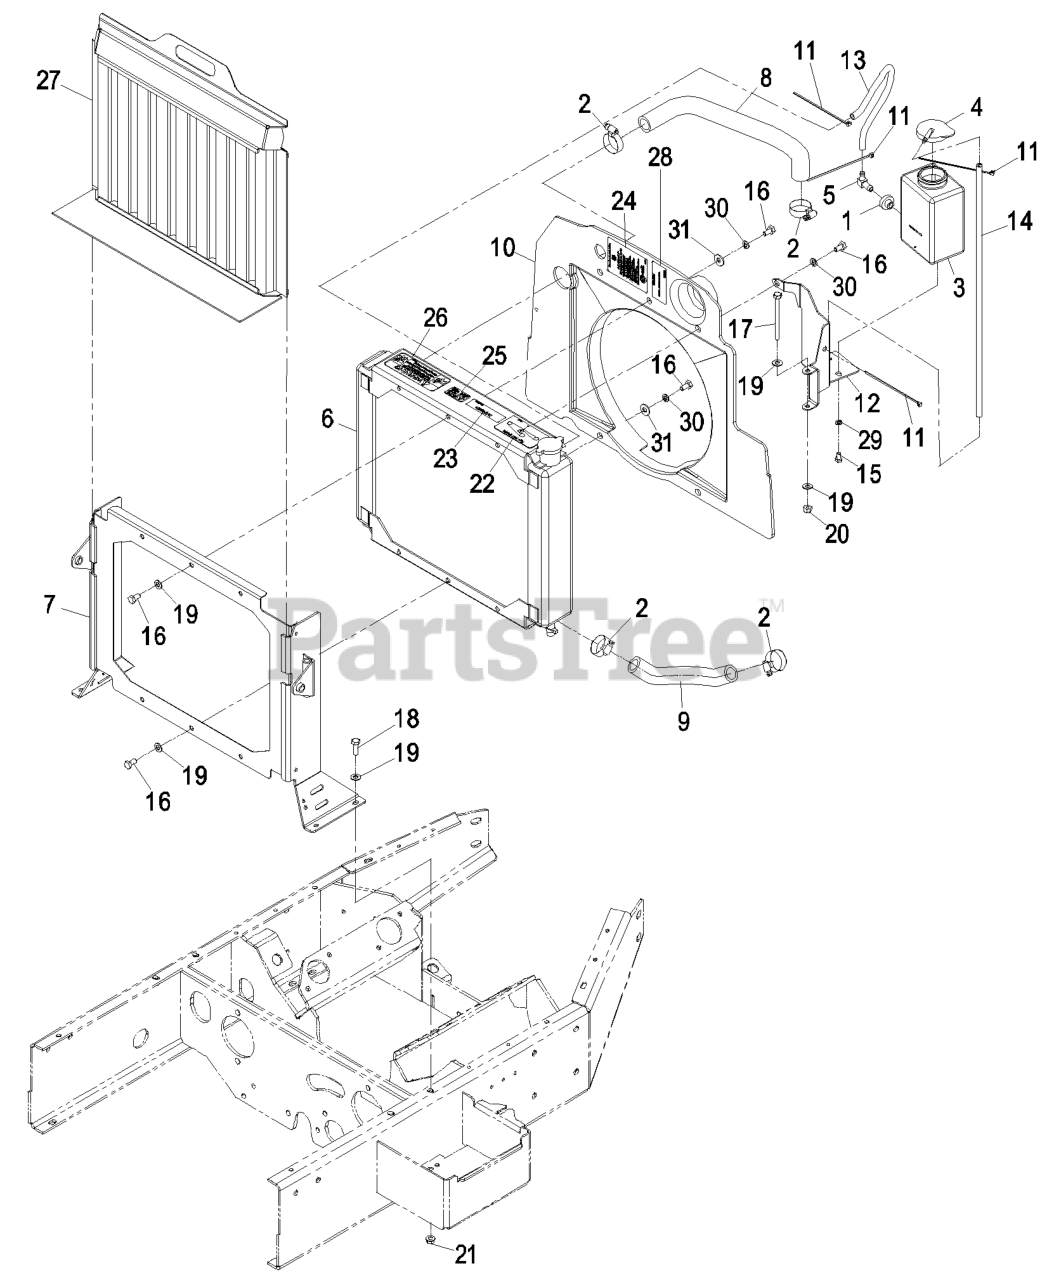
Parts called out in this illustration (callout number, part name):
3	TANK-OVERFLOW
4	CAP-TANK, OVERFLOW
6	ASM,FMZ RADIATOR
7	WLD,RADIATOR SUPPORT
8	HOSE,UPPER RADIATOR
9	HOSE,LOWER RADIATOR
10	ASM,FR25KD SHROUD W/DCLS
11	TIE-CABLE
15	SCREW-HH
16	SCREW-HH
17	SCREW-HH
18	SCREW-HH
19	WASHER-PLAIN
20	NUT-LOCK, NI
22	DECAL-ROUTING, BELT
23	DECAL-COVER, MISSING
24	DECAL,SHELL COOLANT
25	DECAL-CAUTION
26	DECAL-DEVICES, ROTATING
27	ASM,RADIATOR SCREEN
28	DECAL-ANTIFREEZE
29	SCREW-HH
30	WASHER-LOCK
31	WASHER-FLAT
